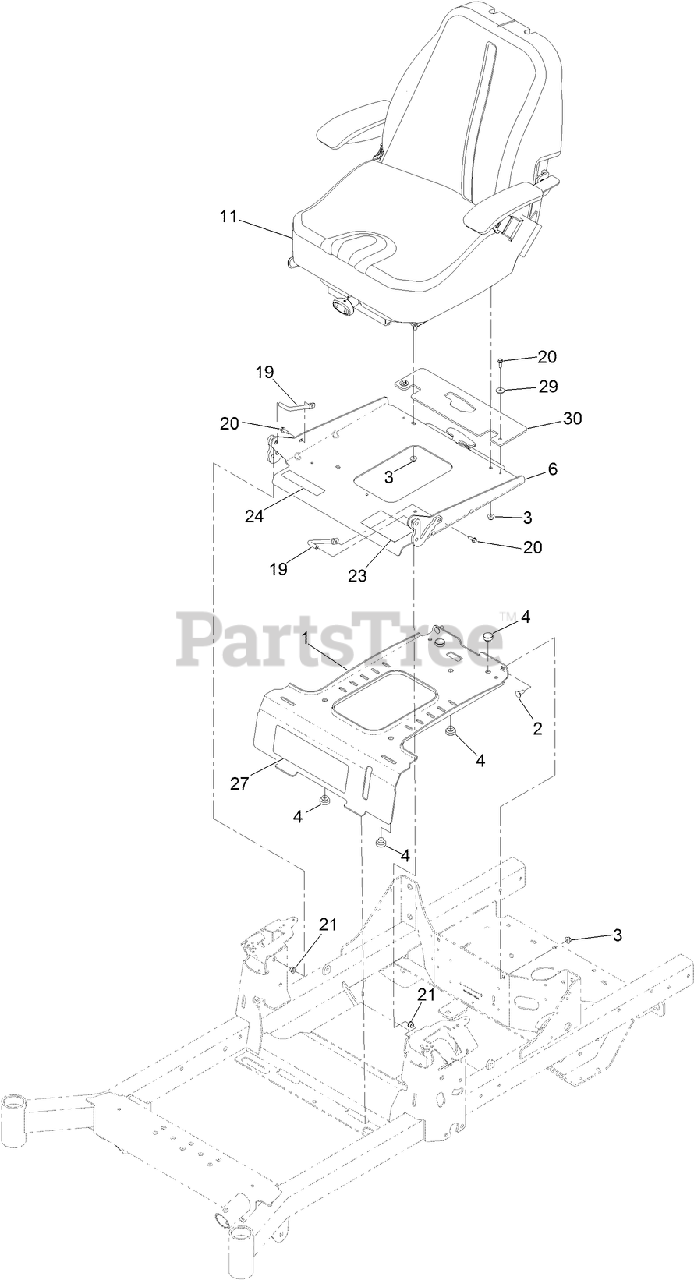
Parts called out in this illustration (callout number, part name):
1	PLATE-RETAINER, TANK
2	SCREW-CARR
3	NUT-HF, NI
4	BUMPER-RUBBER
6	SEAT PAN AND LATCH ASM
11	SEAT ASM
19	PIN-PIVOT, SEAT
20	SCREW-HWH, THREAD ROLL
21	BUSHING-FLANGED
23	DECAL-AID, SERVICE
24	DECAL-LATCH, SEAT
29	WASHER
30	GUARD-SEAT, RUBBER
